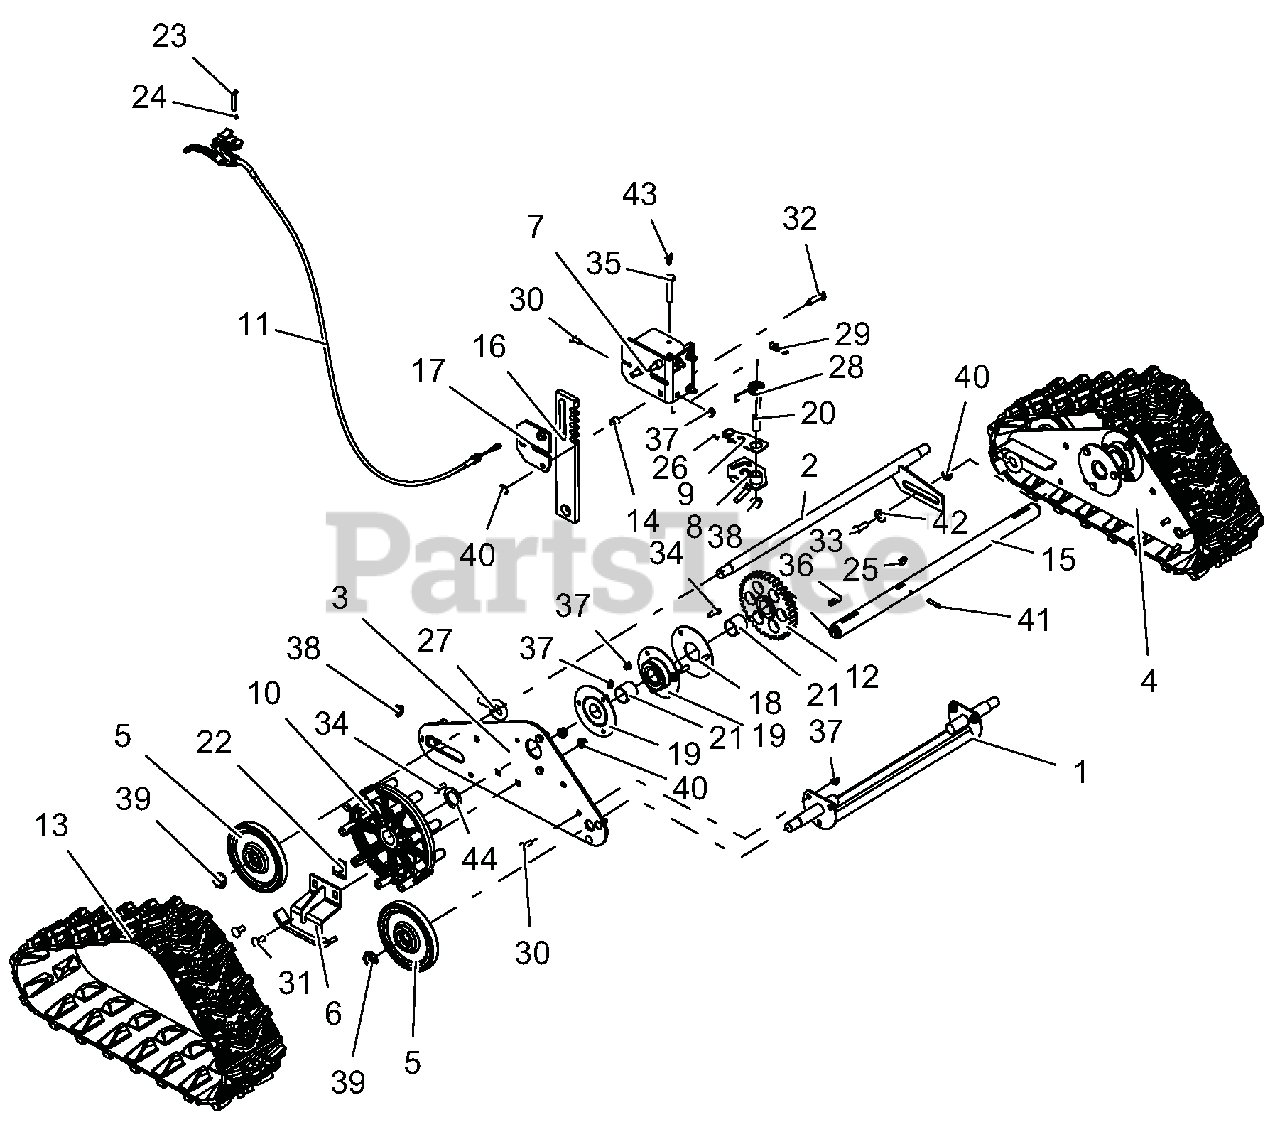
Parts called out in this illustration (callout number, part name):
1	AXLE, FRONT-DELUXE TRACK
2	AXLE, REAR - DELUXE TRACK
3	SIDE PLATE, RH-DELUXE TRACK
4	SIDE PLATE, LH-DELUXE TRACK
5	WHEEL, BOGIE - SINGLE BEARING
6	RUNNER, GUIDE-TRACK
7	BRACKET, HEIGHT ADJUSTER
8	LOCK, HEIGHT ADJUSTER
9	ARM, OVERTRAVEL
10	WHEEL, MACHINED DRIVE
11	CABLE, TRACK REMOTE
12	GEAR, SPUR
13	TRACK, RUBBER
14	SPACER .50 X .32 X .42
15	AXLE, TRACK-DELUXE
16	STOP, HEIGHT ADJUSTER - DELUXE
17	PLATE, HEIGHT ADJUSTER
18	PLATE, BEARING SPACER
19	BRG-FLG 1.003/1.000 3 BOLT
20	BSHG-SLV .385X.500X1.045
21	BSHG-SLV, 1.012X1.125X1.00
22	CLIP, SNAP .625 DIA
23	SCR-MCH .25-20X1.50 OVAL HD
24	WSHR-LK-INT .250 TH TYA
25	KEY-WDRF .25X.750X.313 SAE91
26	PIN-HAIR INT .06X.18X.77
27	BLT-EYE .375-16X.880 YWZC
28	SG-TORS .067X.88
29	SPRING-EXT .047 X .438 X 1.85
30	@BLT-RDHDSQNK .25-20X.75 G5YZ
31	@BLT-RDHDSQNK .31-18X.75 G5YZ
32	@BLT-RHDSHSQNK.31-18X1.25 G5YZ
33	@BLT-HEX .31-18X1.00 GR5 YWZC
34	@BLT-HEX .25-20X.75 GR5 YWZC
35	@BLT-HEX .38-16X1.75 GR5 YWZC
36	KEY-RECT .25X.188X1.00
37	@NUT-LK-CTR-FLG .25-20 YWZC
38	NUT-LK-CTR-FLG .38-16 YWZC
39	@NUT-LK-NYL .625-18 YWZC
40	@NUT-LK-TOP-FLG .31-18 YWZC
41	PIN-ROLL .188X1.25
42	BSHG-FLG .325X.499X.3X.875
43	SCR-TAP .25-20X.50 HWH TR YWZ
44	WSHR-FL-STL 1.010X1.505X.062YZ
